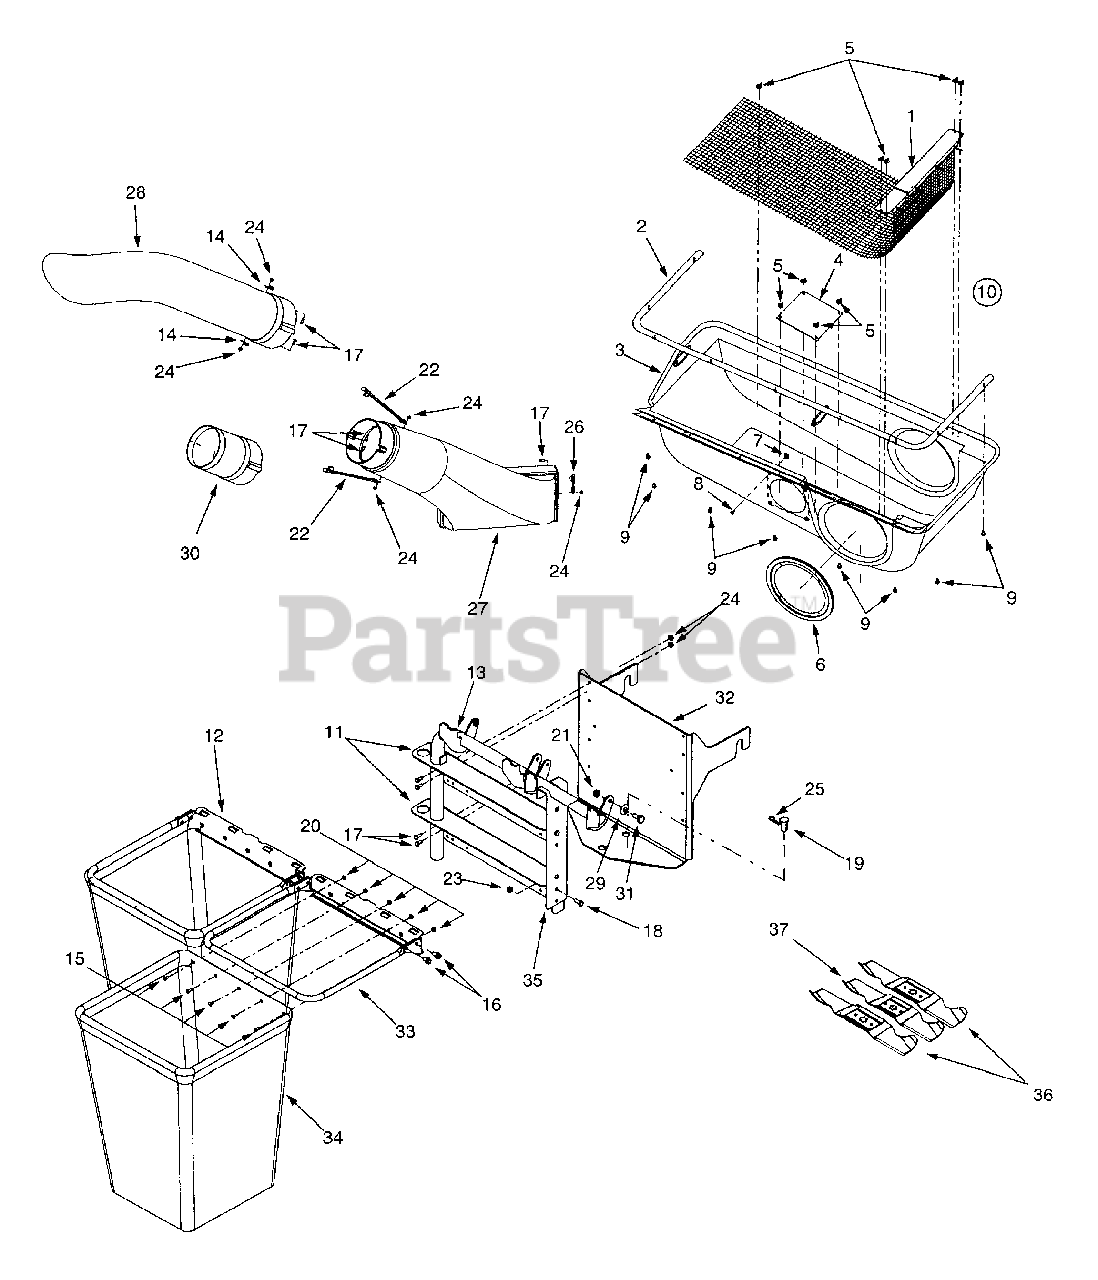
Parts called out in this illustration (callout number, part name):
3	Grass Catcher Cover
4	Plastic Plate, 1/8 x 5.6 sq.
5	Zip Twist Fastener
6	Tube Seal
7	U-Type Speed Nut, #10-24
8	Screw, #10-24 x .5
9	Hex Screw, 1/4-20 x .5
10	Cover Assembly
14	Retainer Hook Bracket
15	Screw, #10-24 x .5
16	Self Tapping Screw, 5/16-18 x .625
17	Hex Cap Screw, 1/4-20 x .62
18	Hex Cap Screw, 5/16-18 x .75
19	Clevis Pin
20	Hex Sems Nut, 10-24
21	Hex Flange Lock Nut, 3/8-16
22	Retainer Strap Assembly
23	Hex Flange Lock Nut, 5/16-18
24	Hex Flange Lock Nut, 1/4-20
25	Internal Cotter Pin, .148 x 3
26	Retainer Strap Assembly
27	Discharge Chute
28	Chute Tube
29	Bell Washer
30	Extension Tube
31	Shoulder Screw, .50 x .27, 3/8-16
34	Bag
36	Star Center Blade, 16.28
37	Star Center Blade, 14.88
